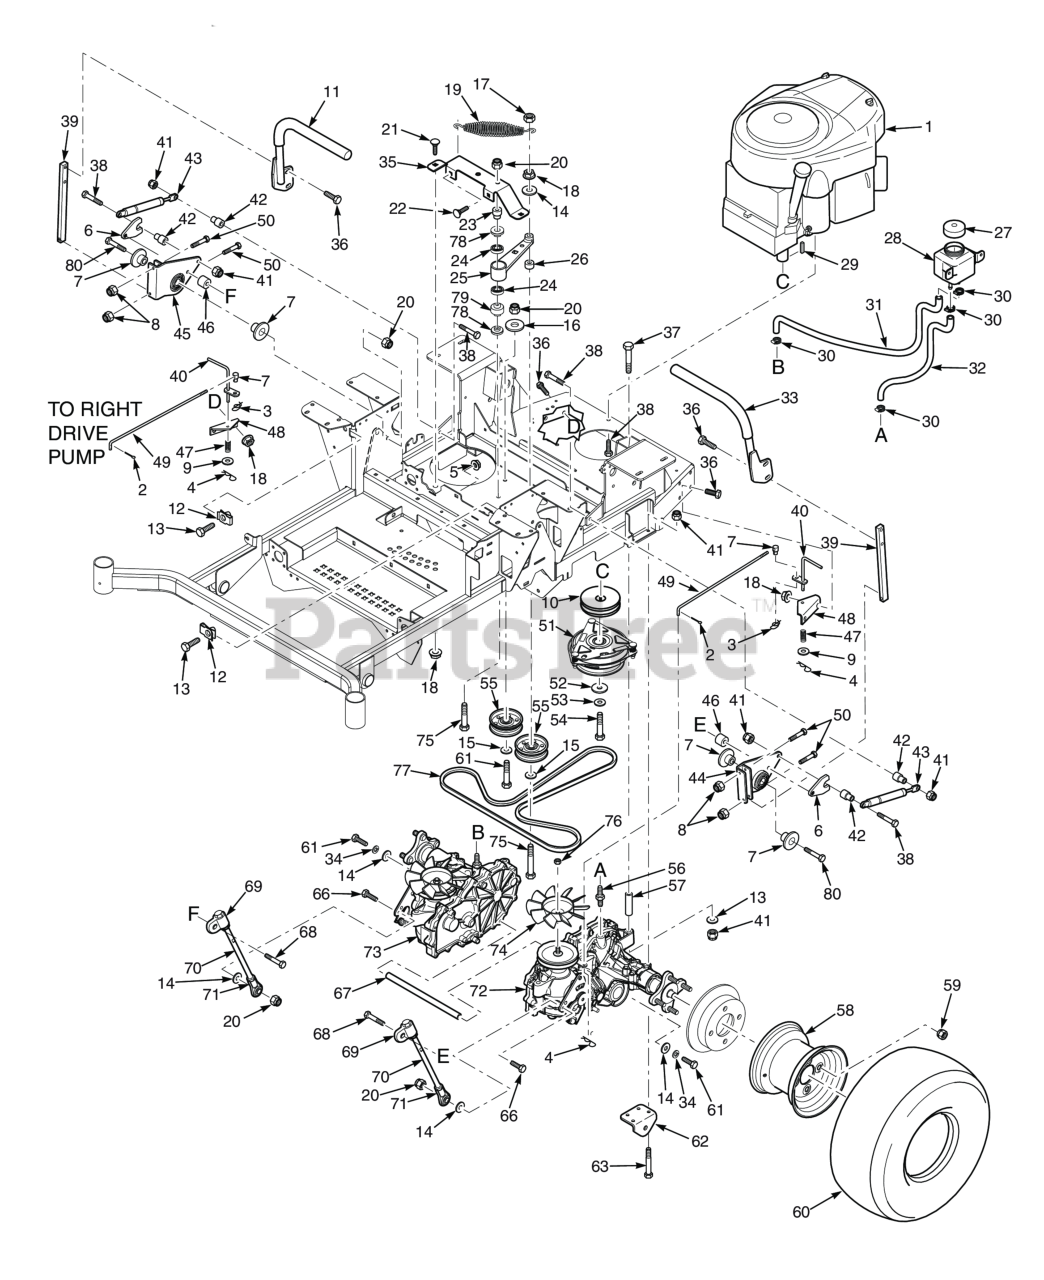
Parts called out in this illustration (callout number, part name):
1	Engine, Kohler - 23CV
2	COTTER PIN, 3/32 X 1"
3	Pin, Rue Cotter 3/8" Diameter
4	HAIR PIN, .08 DIAMETER X 1-3/16"
5	Nut, Serrated Flange 5/16-18 (Right Front Engine Mounting, Briggs and Kohler Only)
6	Nut, Control Linkage
7	Spacer, Linkage
8	HEX, NUT, ELASTIC STOP LOCK, 1/4-20
9	Flatwasher, 1/4" (.312 x .750 x .065")
10	Pulley, 4-1/2" OD - 1.125 Bore (SFZ61)
11	Handle Bar w/Grip
12	U-Nut, 3/8-16 (short)
13	Bolt, Hex Head 3/8-16 x 1-1/4" Special Lock
14	Flatwasher, 3/8" Special (.391 x .938 x .105)
15	Flatwasher, 3/8 (.391 x .938 x .105 HD) Grade 8
16	Flatwasher, 3/8-.406 x 1-1-1/2 x 7 Gauge
17	Bolt, Hex Head 3/8-16 x 1" Ser. Flg.
18	NUT, 3/8-16 SERRATED FLANGE HEX HEAD
19	Spring, Transmission Idler
20	HEX NUT, ELASTIC STOP LOCK, 3/8-16
21	Bolt, Carriage 3/8-16 x 3/4"
22	Bolt, 5/16-18 x .75 RHSN Carriage
23	Shaft Pivot, Idler Arm
24	BEARINGS, BALL, NEUTRAL RETURN
25	Trans. Idler Arm Assy. (Includes 24, 79)
26	Spacer, Idler Pulley - SFZ52
27	Cap, Hydraulic Tank
28	Reservoir Assembly
29	Key, 1/4" x 1/4" x 2-3/4" Pulley Mtg.
29	KEY, 1/4 X 1/4 X 2-1/2"
30	Clamp, Cable 3/4" I.D.
31	Hose, RH Transmission
32	Hose, LH Transmission
33	Handle Bar Assembly, w/Grip
34	Lockwasher, 3/8" Spring, Kawasaki FX / FS
35	Support, Idler Arm
36	Capscrew, 3/8-16 x 1.0" Serrated Flange Hex Hd
37	HEX HEAD BOLT, 5/16-18 X 5"
38	Bolt, Hex Head 5/16-18 x 1-1/2" (Right Front Engine Mounting, Briggs and Kohler Only)
39	Bar, Control Lever
40	Dump Valve Lever
41	HEX NUT, ELASTIC STOP LOCK, 5/16-18
42	Spacer, Pump Dampener
43	Gas Damper
44	Control Link, LH
45	Control Link, RH
46	Spacer, Idler Pulley - SFZ52
47	Spring, Dump Valve Link
48	Bracket, Dump Mounting
49	Rod, Brake Adjustment
50	Bolt, Hex Head, 1/4-20 x 1-1/2"
51	Electric Clutch Assembly - SFZ52 & SFZ61
52	Flatwasher, 7/16-.469 x 1.75 x .25 (48, 52)
53	Flatwasher, 7/16-.469 x 1.75 x .25 (48, 52)
54	HHCS, 7/16-20 X 1.75 W/ PATCH
55	Pulley, 3-1/2" Dia.
56	Fitting, 9/16" O-Ring x 3/8" Hose
57	Spacer, Axle - SFZ52
58	Rim w/Valve Stem (52)
58	Rim w/Valve Stem, (Black) - SPZ52
59	Wheel Nut, 1/2-20 x 13/16
60	Wheel Assembly, 22 x 10.5-12 (SPZ52)
60	Tire/Rim Assy, (Black) 22 x 10.5-12 (SPZ52)
60	Tire, 22 x 10.5-12 (SPZ52)
61	Capscrew, Hex Head 3/8-16 x 2-1/2"
62	Bracket, Push Arm Link
63	Bolt, Hex Head 5/16-18 x 3.00"
64	Clip, Brake Lever (order through Hydro-Gear)
65	Lever, Brake (order through Hydro-Gear)
66	Bolt, Hex Head, 3/8-16 x 1-1/2"
67	Spacer, Axles
68	Capscrew, Hex Head 3/8-16 x 2.0"
69	Rod End, Adjustable 3/8-24
70	Linkage, Pump - SFZ52
71	Stake, Rod End Assembly
72	Transaxle Assy., LH (ZL-KCEF-3LKG-1NXX) SFZ52
73	Transaxle Assy., RH (ZL-GCEF-3LKG-1NXX) SFZ52
74	Fan (order through Hydro-Gear)
75	Capscrew, Hex Head 3/8-16 x 3.25"
76	Fan Nut (order through Hydro-Gear)
77	Belt, Transmission Drive - SFZ52
78	Spacer, Controls
79	Spacer, Bearing
80	Capscrew, Hex Head 3/8-16 x 2.0"
